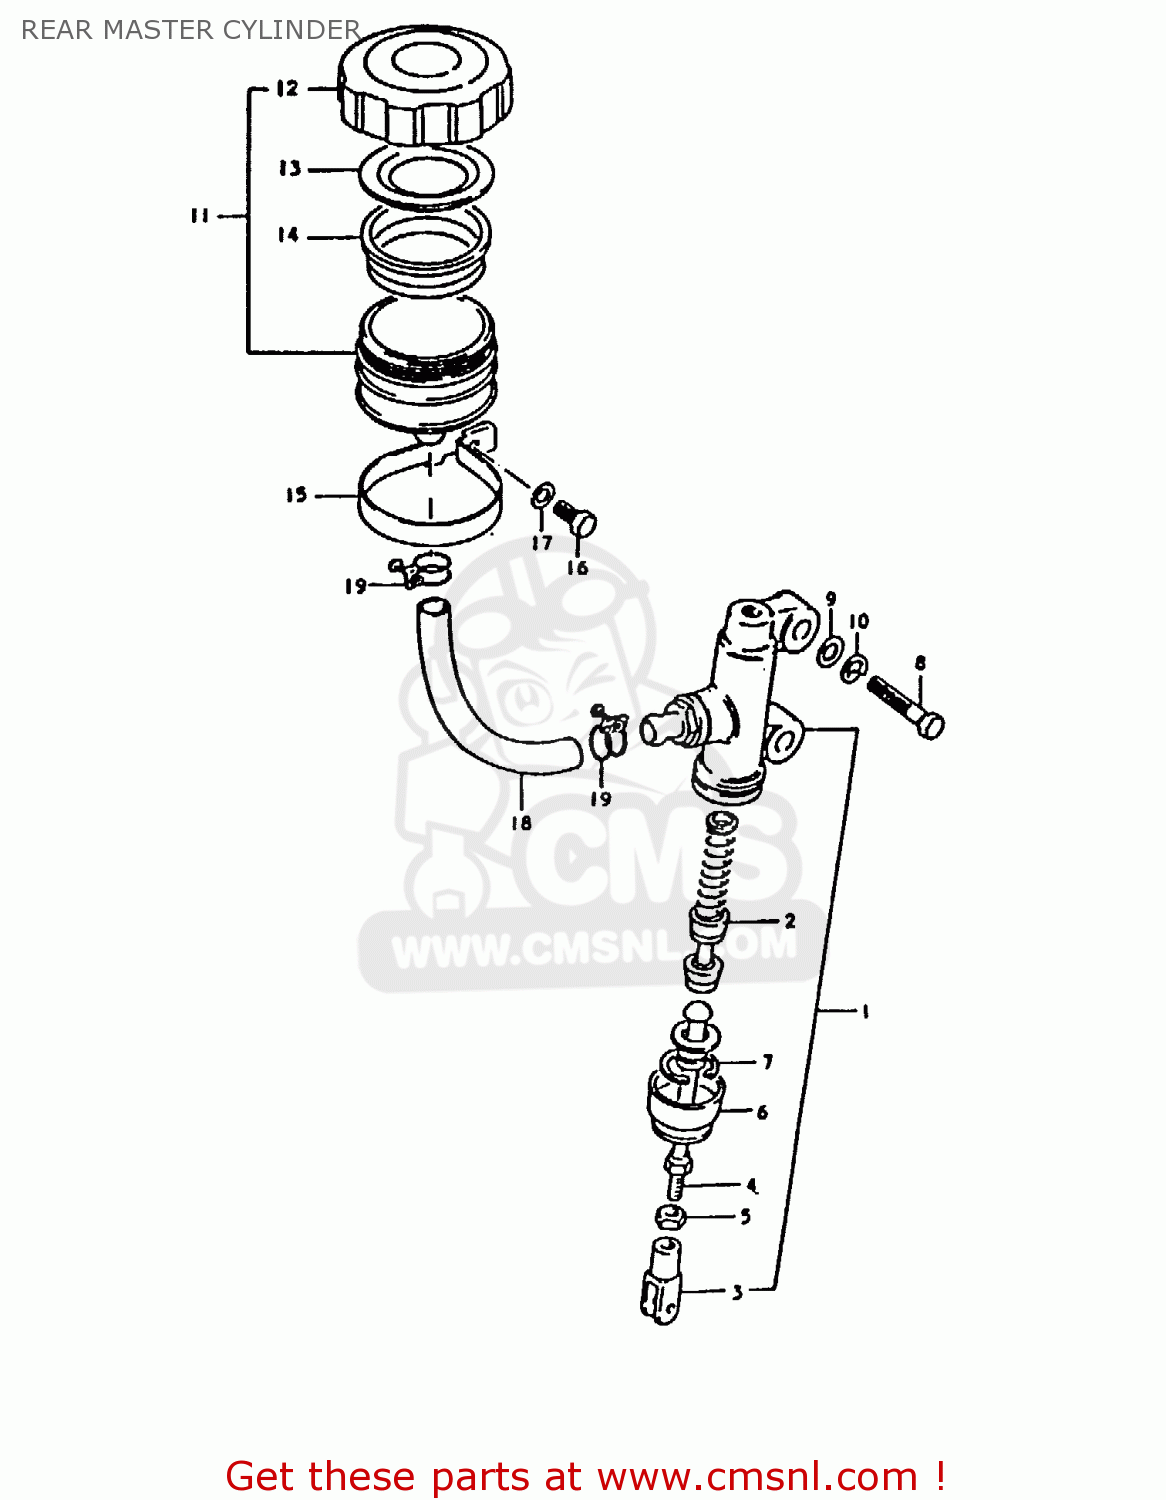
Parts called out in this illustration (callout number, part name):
1	CYLINDER ASSEMBLY,REAR MASTER
2	PISTON/CUP SET
3	YOKE
4	ROD,PUSH
5	NUT
6	BOOT
7	CIRCLIP
8	BOLT (8X30)
9	WASHER
10	LOCK WASHER
11	TANK ASSEMBLY,RESERVOIR
12	CAP
13	PLATE,DIAPHRAGM
14	DIAPHRAGM
15	CLAMP
16	BOLT, UPPER
17	LOCK WASHER
18	HOSE,RESERVOIR TANK
19	CLAMP
